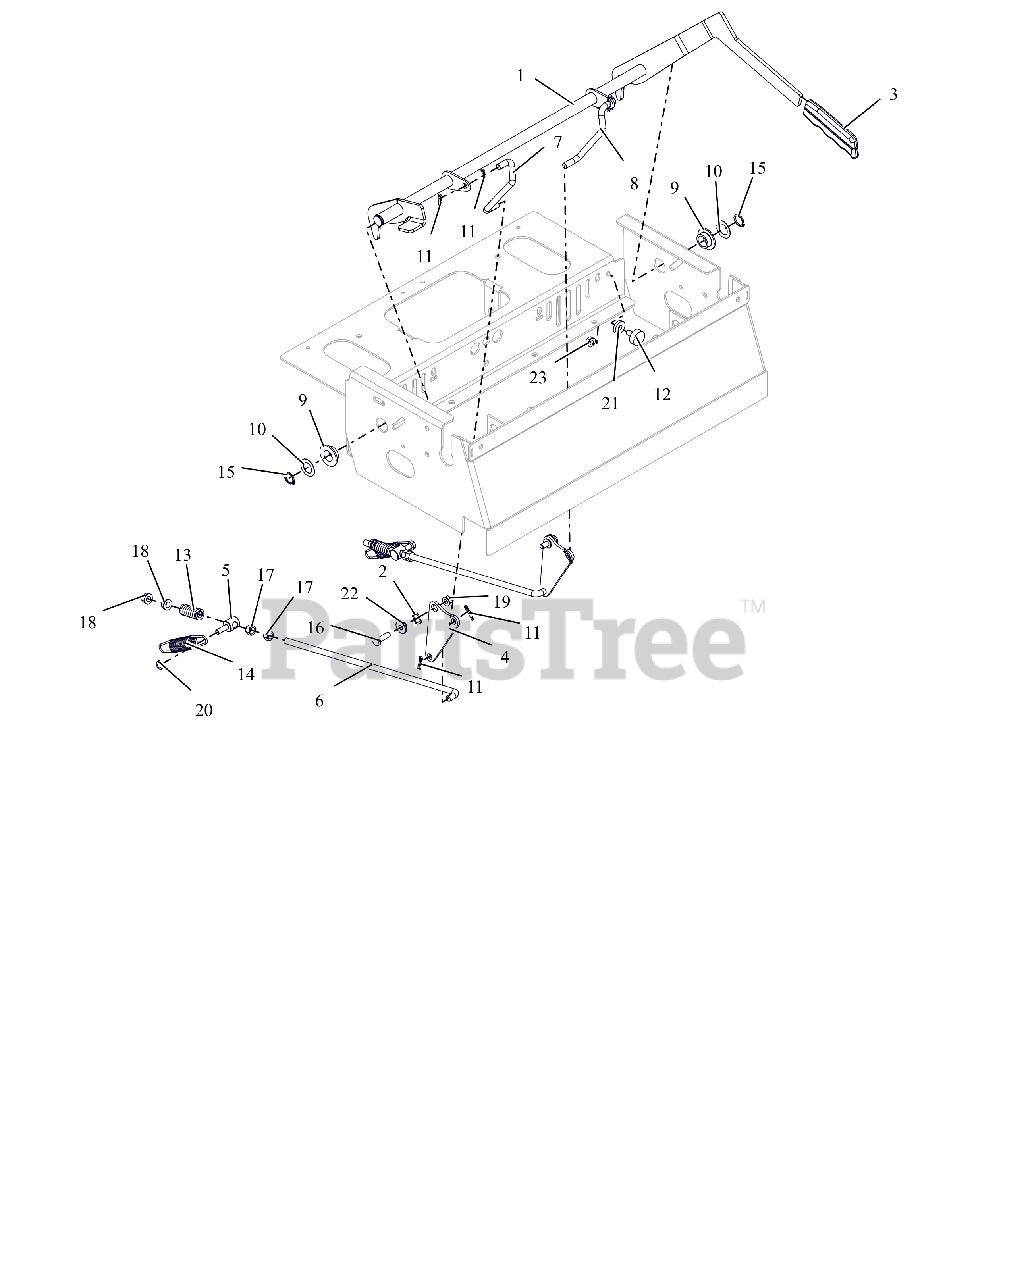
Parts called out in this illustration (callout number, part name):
1	WLDMT, PT200/400 PARK BRAKE
2	WAVE WASHER .531X.781X.125FH
3	GRIP, PARKING BRAKE (YELLOW)
4	PLATE, BRAKE PIVOT
5	TRUNNION, .38-16
6	ROD, BRAKE ADJ.
7	LINKAGE, RH BRAKE ACTUATING
8	LINKAGE, LH BRAKE ACTUATING
9	BSHG-FLG .762X1.48X.44 NYL
10	WSHR-HDND-THRST .758X1.23X.031
11	PIN, HAIR #225 .072X1.09
12	BUMPER, RUBBER
13	SG-COMP .142 X .710 X 1.75
14	SPRING-TENS .105X.850X.4.880
15	RG-RTNG-EXT .689X.078
16	BLT,HEX .31-18X1.00 G5 ZCC
17	NUT-STD .375-16 G2 ZCC
18	NUT, SPNLK-FLG .38-16 G5 ZCC
19	NUT-LK-TOP-FLG .312-18 GF ZCC
20	NUT-LK-CTR-JAM .312-18 GB ZCC
21	WSHR, FLT .328X.870X.179 ZCC
22	BSHG-FLG .32X.500X.344X.880
23	NUT,SPNLK-FLG .31-18 G5 ZCC
